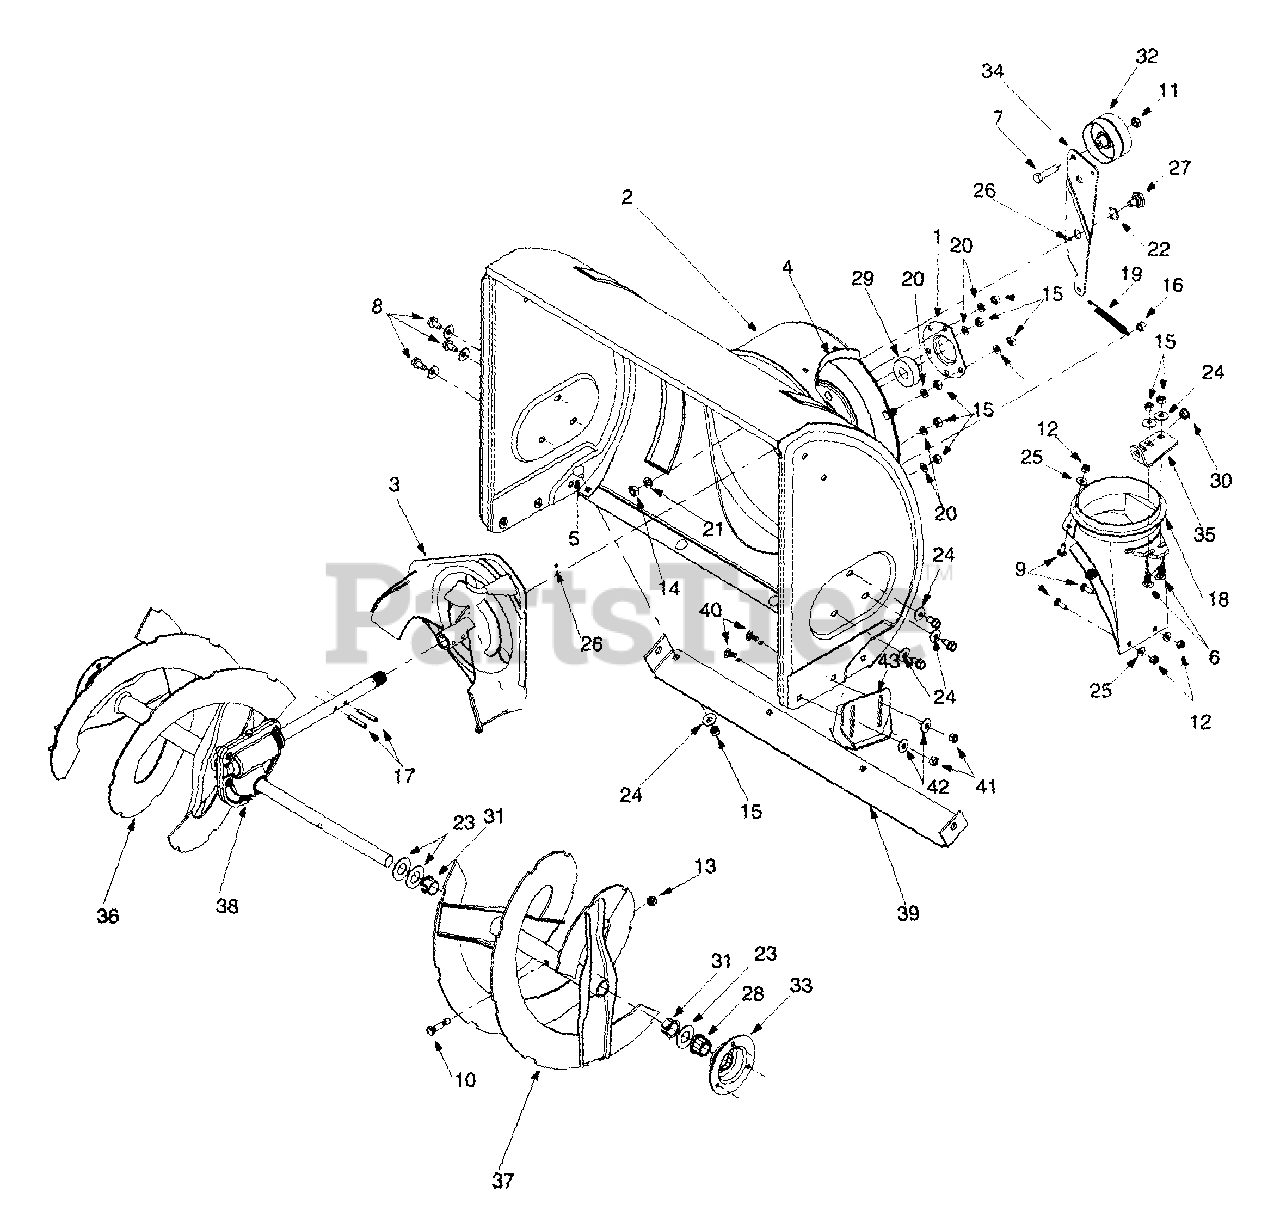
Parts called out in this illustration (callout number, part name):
1	Bearing Housing
5	Carriage Bolt 5/16-18 x .62"
6	Carriage Bolt 5/16-18 x .75" Gr.2
7	Hex Screw 3/8-24 x 1.5" Gr.5
8	Hex Washer Head Self-Tapping Screw 5/16-18 x .62"
9	Carriage Screw 1/4-20 x .75"
10	Shear Bolt 5/16-18 x 1.5"
11	Jam Nut 3/8-24
12	Hex Lock Nut 1/4-20
13	Hex Lock Nut 5/16-18
14	Hex Nut 3/8-16 Gr.2
15	Hex Nut 5/16-18 Gr.5
16	Hex Patch Nut 5/16-18
17	Spiral Pin
18	Chute Adapter
19	Extension Spring
20	Lock Washer
21	Lock Washer
22	Wave Washer
23	Flat Washer
24	Belleville Washer
25	Flat Washer
26	Grease
27	Shoulder Screw
28	Hex Flange Bearing
29	Flange Ball Bearing
30	Bushing
31	Flange Bushing
32	Flat Idler
40	Carr. Bolt: 5/16-18 x 0.75
41	Hex Nut: 5/16-18 Gr.5
42	Belleville Washer
